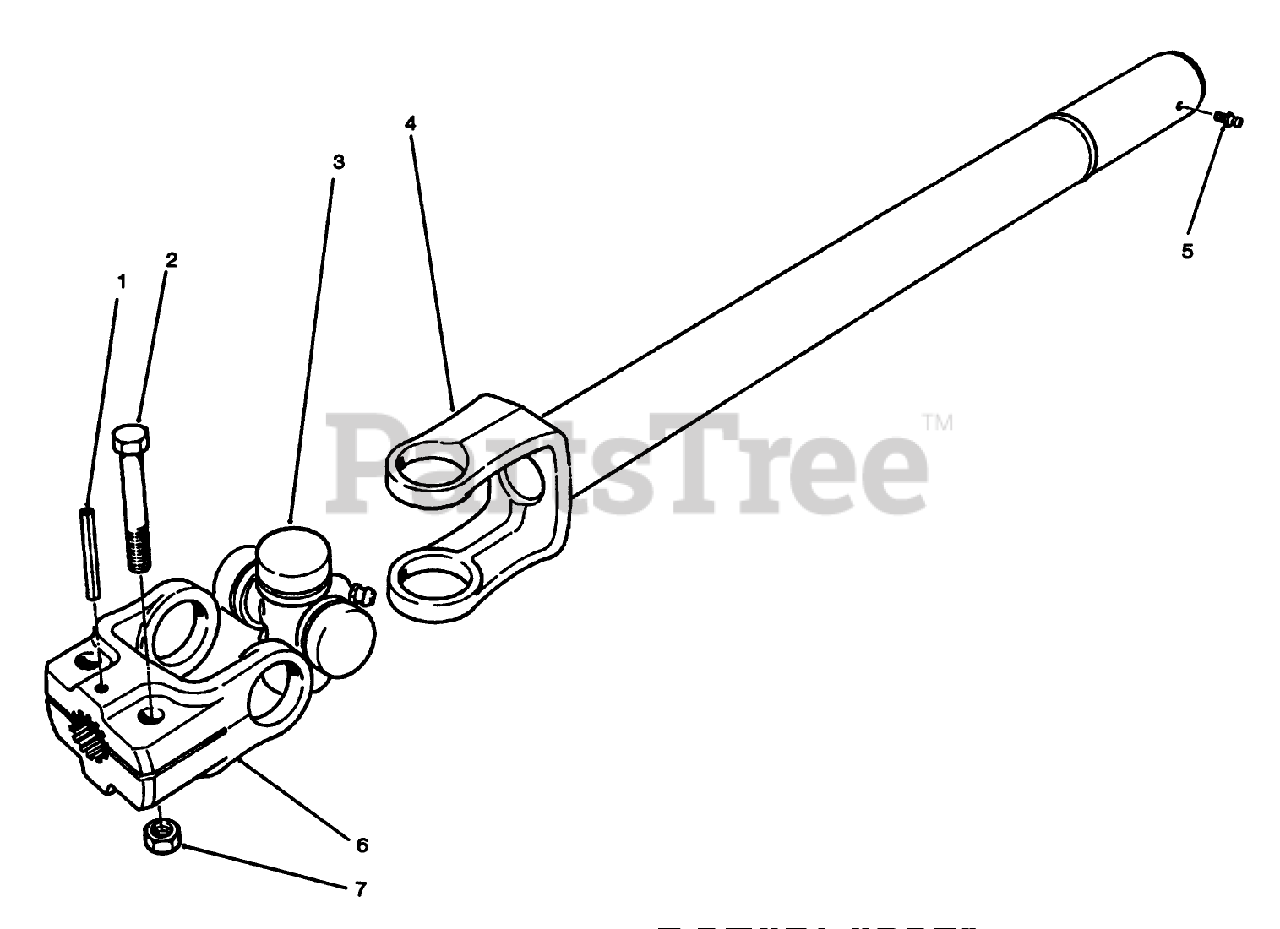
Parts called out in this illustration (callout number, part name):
1	PIN-ROLL
2	SCREW-HH
3	U-JOINT KIT
4	TUBE HALF-SLIP YOKE B
5	FITTING-STRAIGHT
6	YOKE - SPLIT FLANGE
7	NUT-LOCK, SIDE
